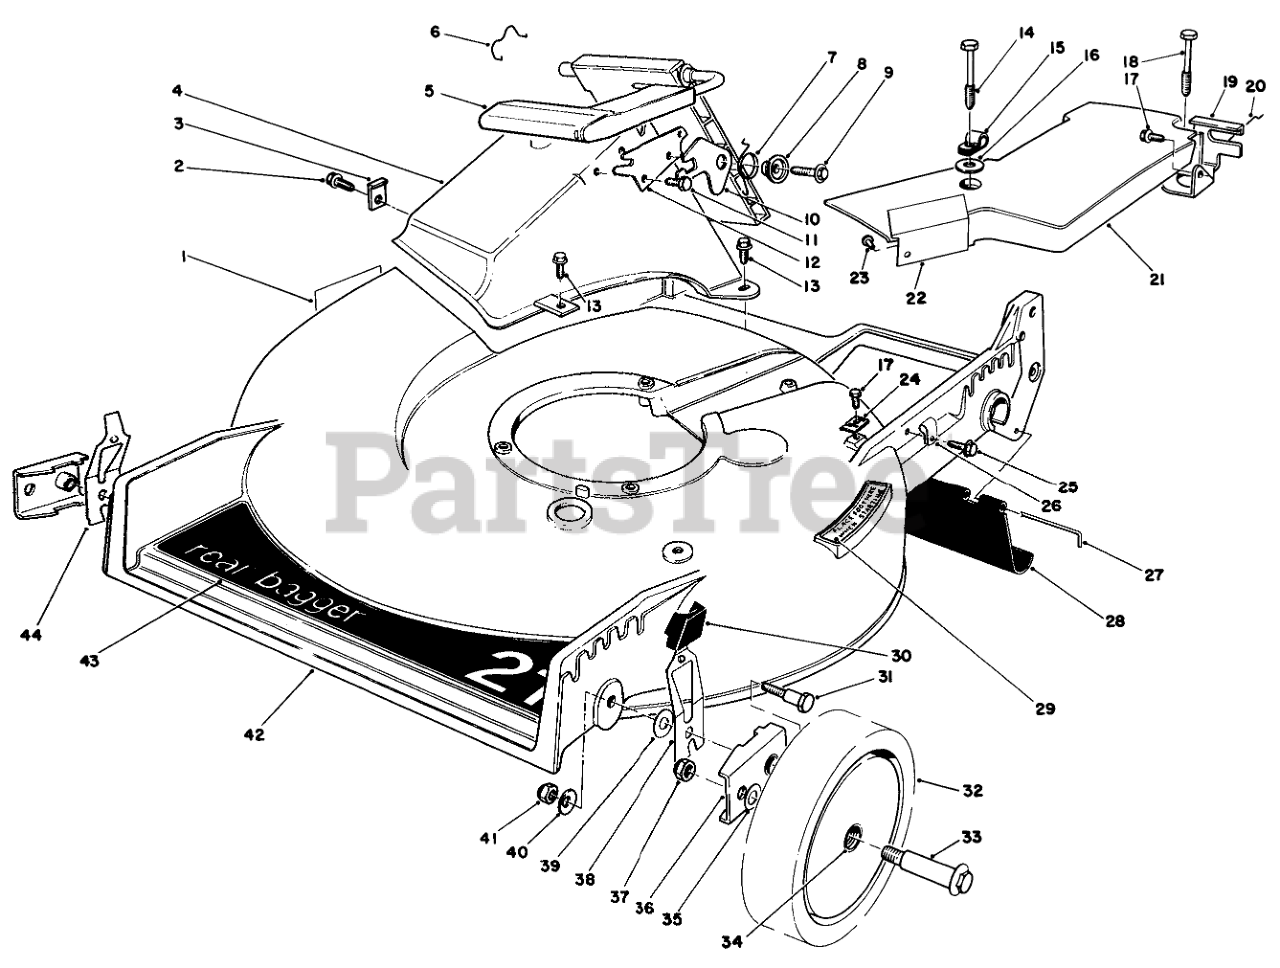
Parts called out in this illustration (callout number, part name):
1	DECAL-DANGER
2	SCREW
3	TUNNEL CLIP
4	Tunnel Discharge
5	Discharge Door Assembly
6	DOOR RET SPRING
7	TORSION SPRING
8	DOOR SPACER
9	SCREW-HWH
10	SAFETY LATCH
11	SCREW-PLASTITE
12	DOOR LATCH PLATE
13	SCREW-HWH
14	SCREW-SPECIAL
15	CLAMP-CABLE
16	WASHER
17	SCREW-HWHTF
18	SCREW-HHFTF
19	Bracket-Traction Adj.
20	RETAINER-CABLE
21	Belt Cover Assembly (Incl. Ref. #22 & 23)
22	HEAT SHIELD
23	RIVET-HEAD, FLAT
24	Cable Clamp
25	SCREW
26	CLAMP-CABLE
27	ROD-SHIELD
28	SHIELD-TRAILING
29	STEP PAD DECAL
30	KNOB-ARM
31	PIVOT SCREW
32	Wheel & Tire Assembly (Incl. Ref. #34)
33	WHEEL BOLT
34	BUSHING
35	WASHER
36	HP PIVOT ARM ASM
37	NUT-LOCK
38	L. HP SPRING ARM ASM
39	WASHER-PIVOT
40	WASHER-BELLEVILLE
41	NUT-LOCK, NI
42	Housing (Incl. Ref. #1, 13 & 29)
43	DECK DECAL
44	R HP SPRING ARM ASM
